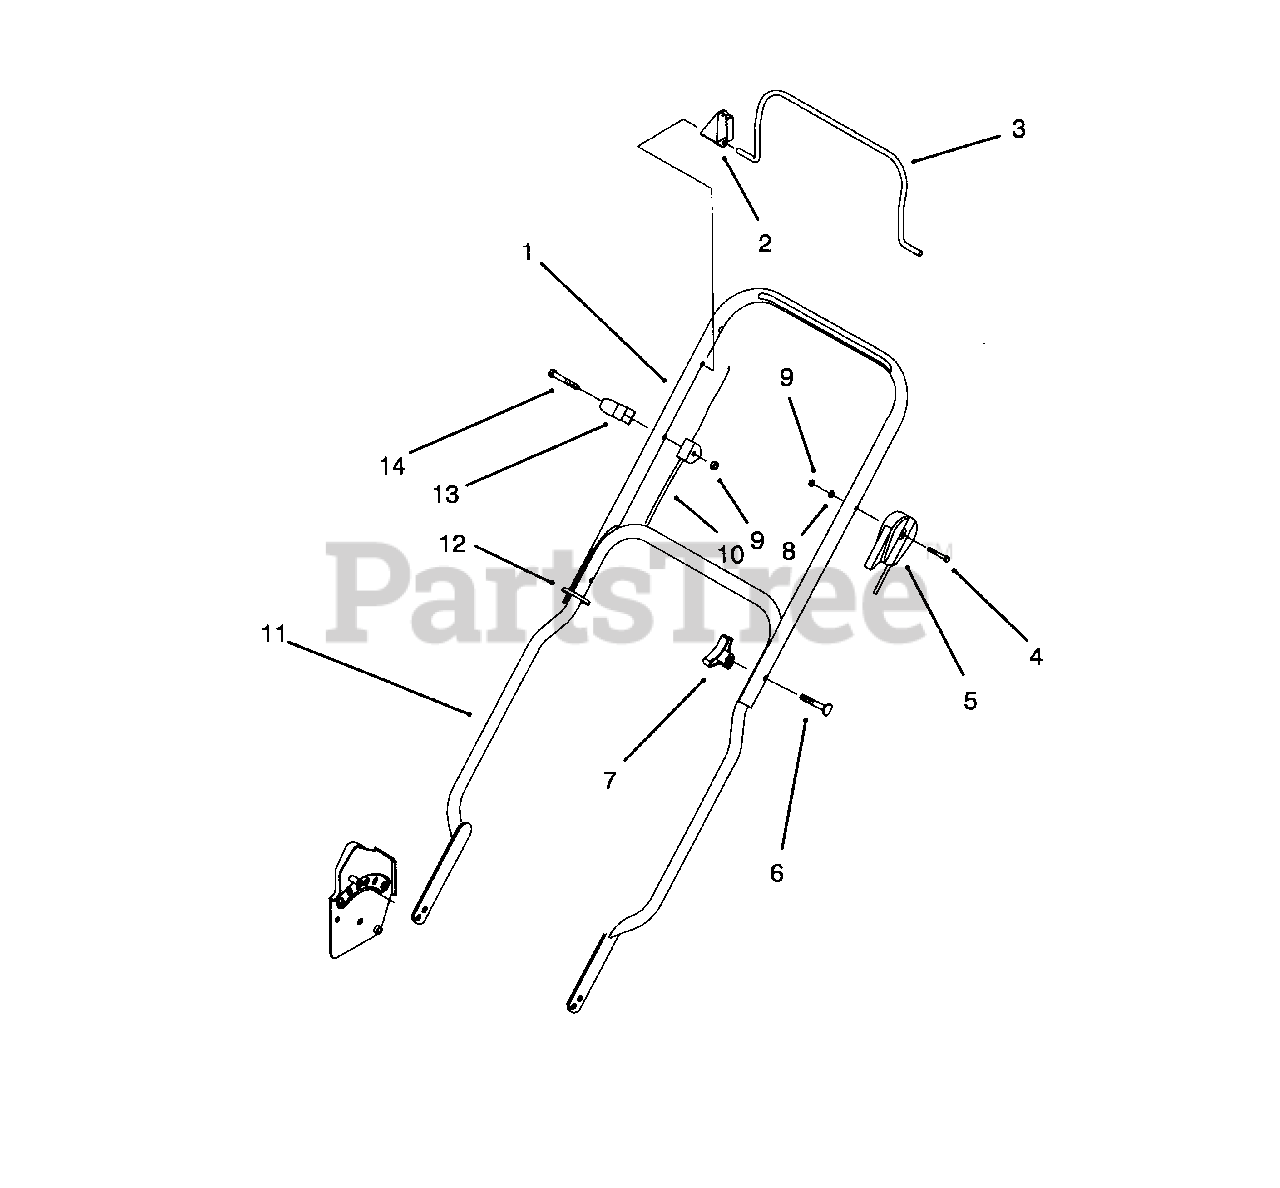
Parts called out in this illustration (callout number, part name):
1	Handle-Upper
2	Stop-Pivot
3	Bail-Flywheel Brake
4	Screw-Hex Hd. Cap
5	Cable-Throttle
6	Screw-Handle
7	Knob-Handle
8	Washer
9	Nut-Lock
10	Cable-Flywheel Brake
11	Handle-Lower
12	Strap-Tie
13	Guide-Rope
14	Screw-Hex Hd. Cap
